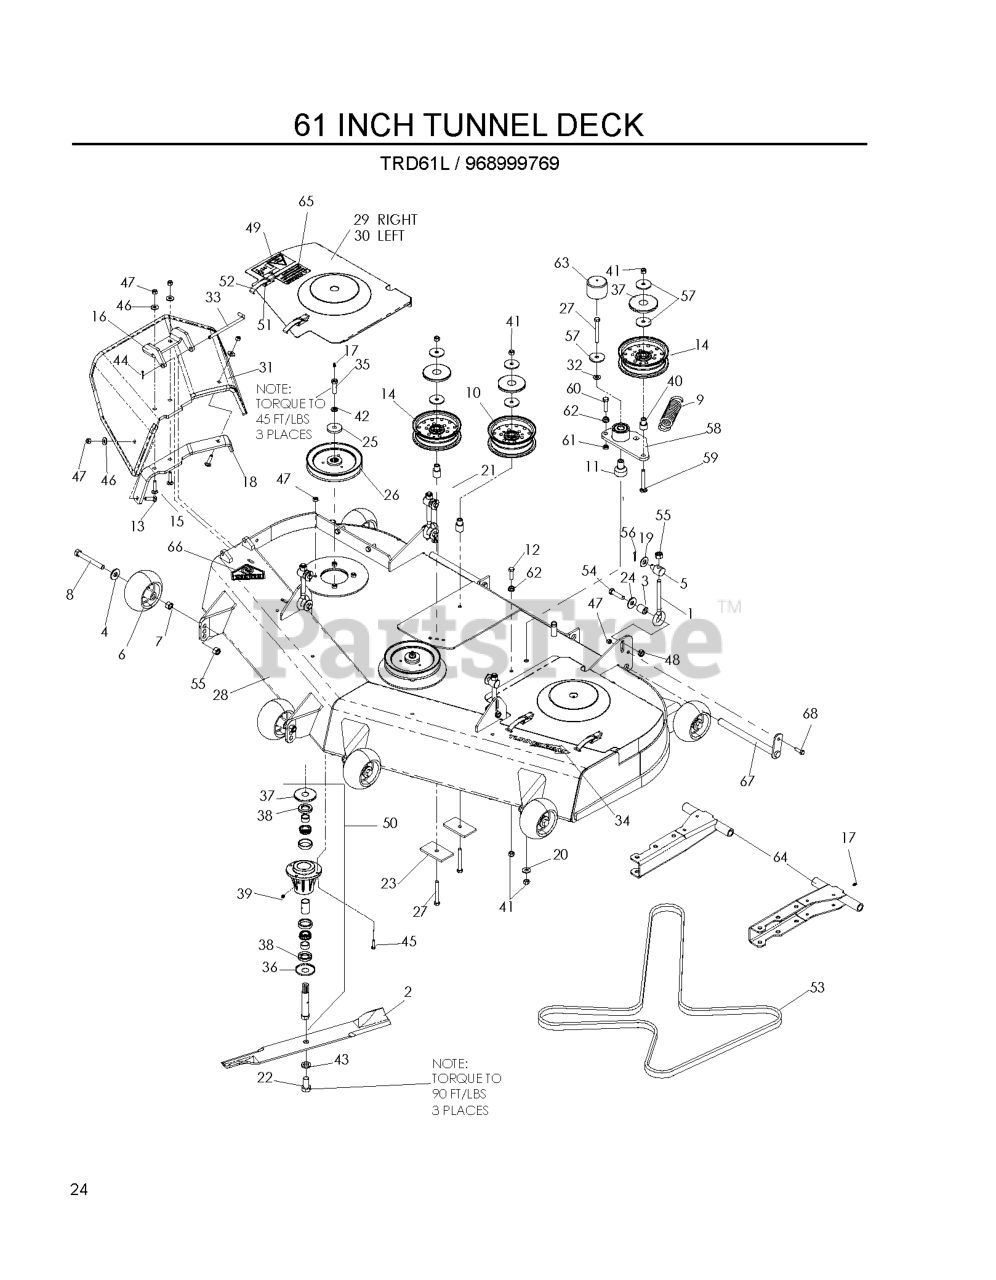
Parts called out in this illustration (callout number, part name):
2	BLADE OEM 21" (61" DECK)
4	WASH USS FLAT 1/2
6	GAUGE WHEEL
7	NUT HEX 1/2
8	HHB, 1/2-13X4
9	DECK SPRING
10	IDLER PULLEY (TALL)
11	PIVOT, BEARING
12	HCS 3/8C X 1 1/4 GR5
13	BOLT, CARRIAGE 5/16X1-1/4
14	IDLER PULLEY
15	RHSNB 5/16-18 X 1-1/2 GR 5 ZD
16	PIVOT BRACKET - RUBBER CHUTE
17	ZERK
18	BRACKET, REINF-CHUTE
19	WASHER 1/2 FLAT
20	WASHER 3/8 FLAT
21	IDLER BUSHING
22	HCS 5/8F X 1 1/4
23	SUPPORT PLATE
24	SPRING WASHER - .50
25	SPINDLE WASHER
26	PULLEY, 61
27	HCS 3/8C X 3
28	DECK W/DECALS 61" HUS
29	61 BELT SHIELD ASM - RH
30	61 BELT SHIELD ASM - LH
31	CHUTE, RUBBER DISCHARGE 52/61"
32	WASHER 3/8 SAE FLAT
33	PIN, CHUTE PIVOT
34	DECAL, TUNNEL RAM 8"
35	HCS 7/16-20 GD 8 SPEC
36	BOTTOM DUST CAP
37	TOP DUST CAP
38	SHAFT SEAL
39	PLUG-VENTED
40	BUSHING, IDLER
41	NUT 3/8-16 NYLOC
42	WASHER 7/16 LOCK
43	LOCKWASHER 5/8
44	RP_COTTER PIN 1/8 X 3/4
45	HCS 5/16C X 1 1/4
46	WASHER 5/16 FLAT
47	NUT 5/16 NYLOC
48	NUT 7/16C CENTERLOCK
49	DECAL, EURO SEVERING
50	HOUSING ASM, 52/61
51	RIVET, BLIND, 5/32 DIA
52	DRAW LATCH
53	DECK BELT 61
54	HCS 7/16 - 14 X 1 3/4
55	NUT 1/2-13 HEX NYLOC ZD
56	PIN COTTER 1/8 X 1 ZD
57	WASHER, 3/8 SPEC
58	ARM-IDLER W/BRG
59	RHSNB 3/8-16 X 2.75
60	HCS 3/8-16 X 1-1/2
61	NUT 3/8-16 HEX JAM
62	NUT 3/8C WHIZ
63	CAP, VINYL
64	STRUT WELDMENT, TRD
65	DECAL, CAUTION
66	DECAL, CPSC
